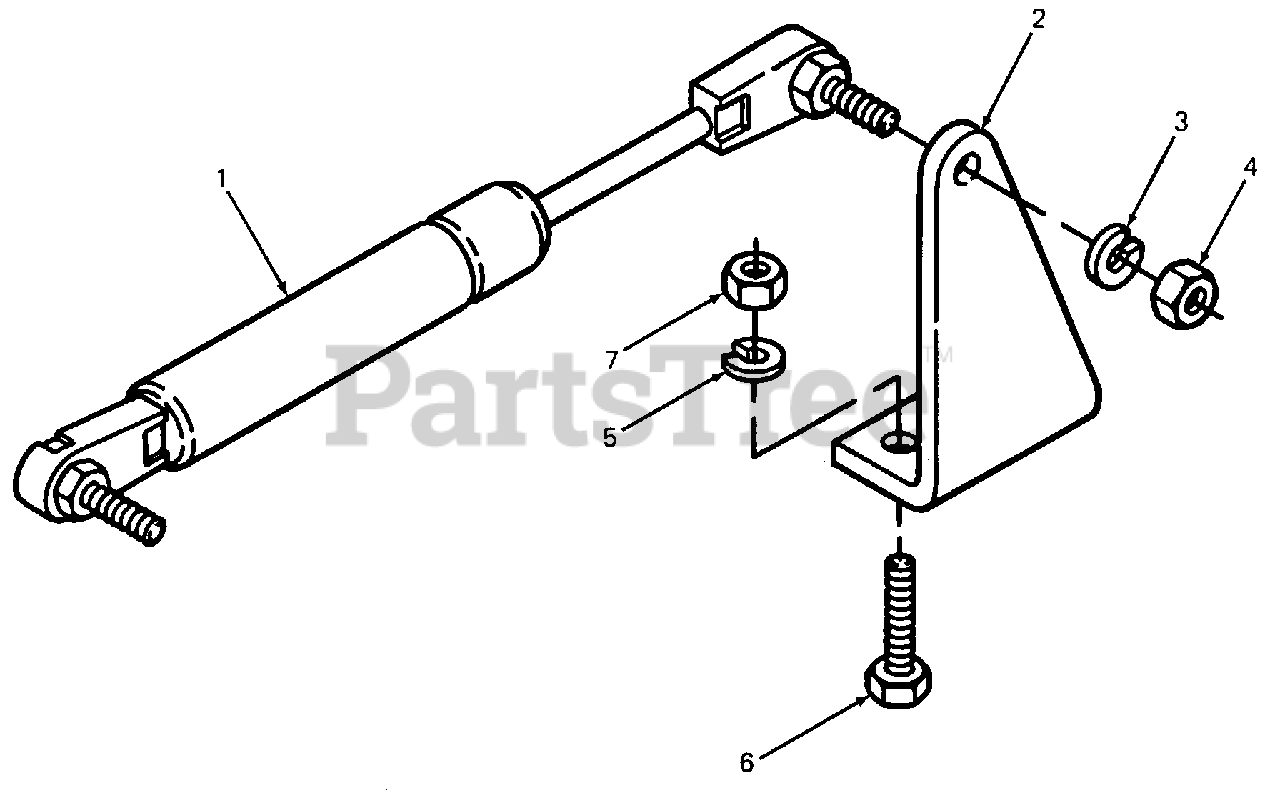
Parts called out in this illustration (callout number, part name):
1	Spring Assy, Gas
2	Bracket, Spring
3	Washer, Lock, 5/16
4	Nut, 5/16-18 GR 5
5	Washer, Lock, 5/16
6	Bolt, 5/16-18 X 7/8 Lg GR 5
7	Nut, 5/16-18 GR 5
